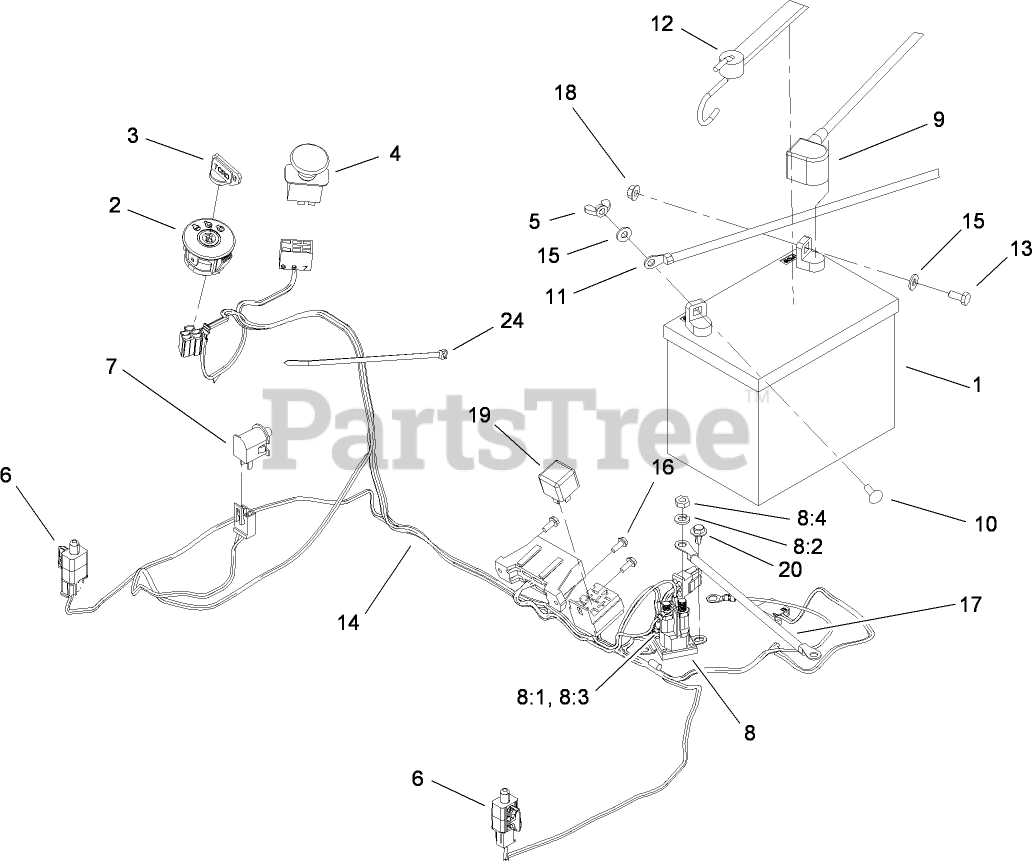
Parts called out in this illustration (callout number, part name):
2	SWITCH-IGNITION
3	KEY-IGNITION
4	SWITCH-PTO,ON-ON-NONE
5	NUT-WING
6	SWITCH
7	SWITCH-BAIL
8:1	WASHER-LOCK
8:2	WASHER-LOCK
8:3	NUT-HEX
8:4	NUT-JAM
9	CABLE-BATTERY, RED
10	BOLT-CARR
11	CABLE-BATTERY, BLACK
12	HOLDDOWN-BATTERY
13	SCREW-HH
15	WASHER-FLAT
16	SCREW-TAPTITE
17	CABLE-BATTERY, RED
18	NUT-HF
19	RELAY
20	SCREW-HHFTF
24	TIE-CABLE
